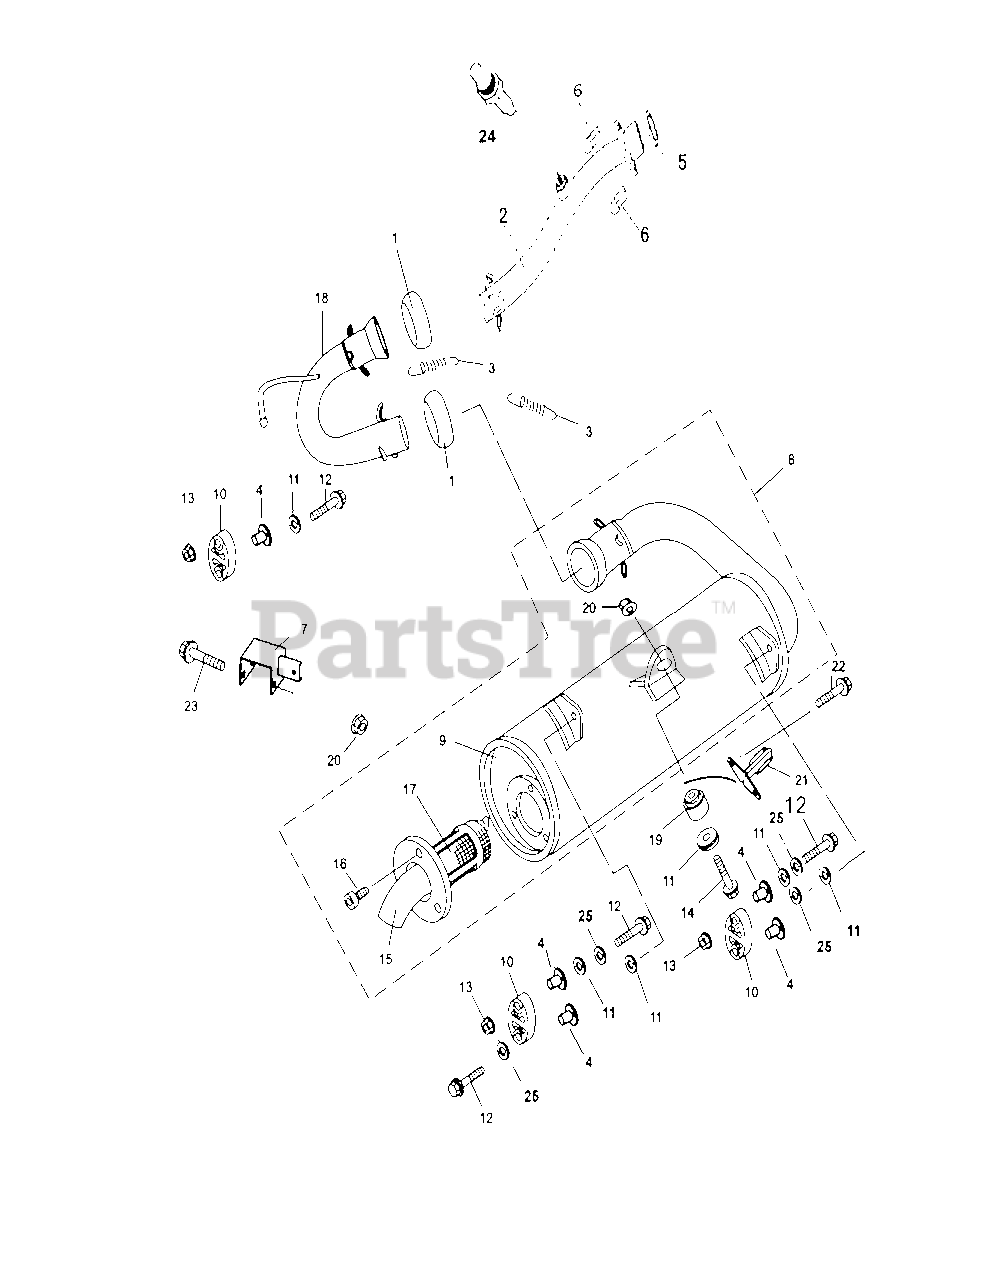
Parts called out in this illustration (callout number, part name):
1	Muffler Sealing Boot
2	Exhaust Pipe I (EFI Engine)
3	Tension Spring XI
4	Bushing 6.5x9x22x17
5	Exhaust Pipe Gasket
6	Nut M8x32
7	Exhaust Pipe Hanging Clamp
8	Muffler Parts
9	Muffler Welded Assembly
10	Damping Pad,Mufflier
11	Stainless Steel Heat Insulation Pad
12	Hexagon Flange Bolt M6x30
13	Hexagon Flange Nut M6
14	Hexagon Flange Bolt M8x45
15	End of Exhuast Pipe
16	Hexagon Socket Head Bolt M6x20
17	Fireproofing Net, Muffler
18	Exhaust Pipe II
19	Suspension Bushings
20	Hexagon Flange Lock Nut M8 (Metallic Insert)
21	Muffler Fixed Seat
22	Hexagon Flange Bolt M8x20
23	Hexagon Flange Bolt M8x70
24	Oxgyen Sensor Assy(EFI)
25	Spring Washer -6
